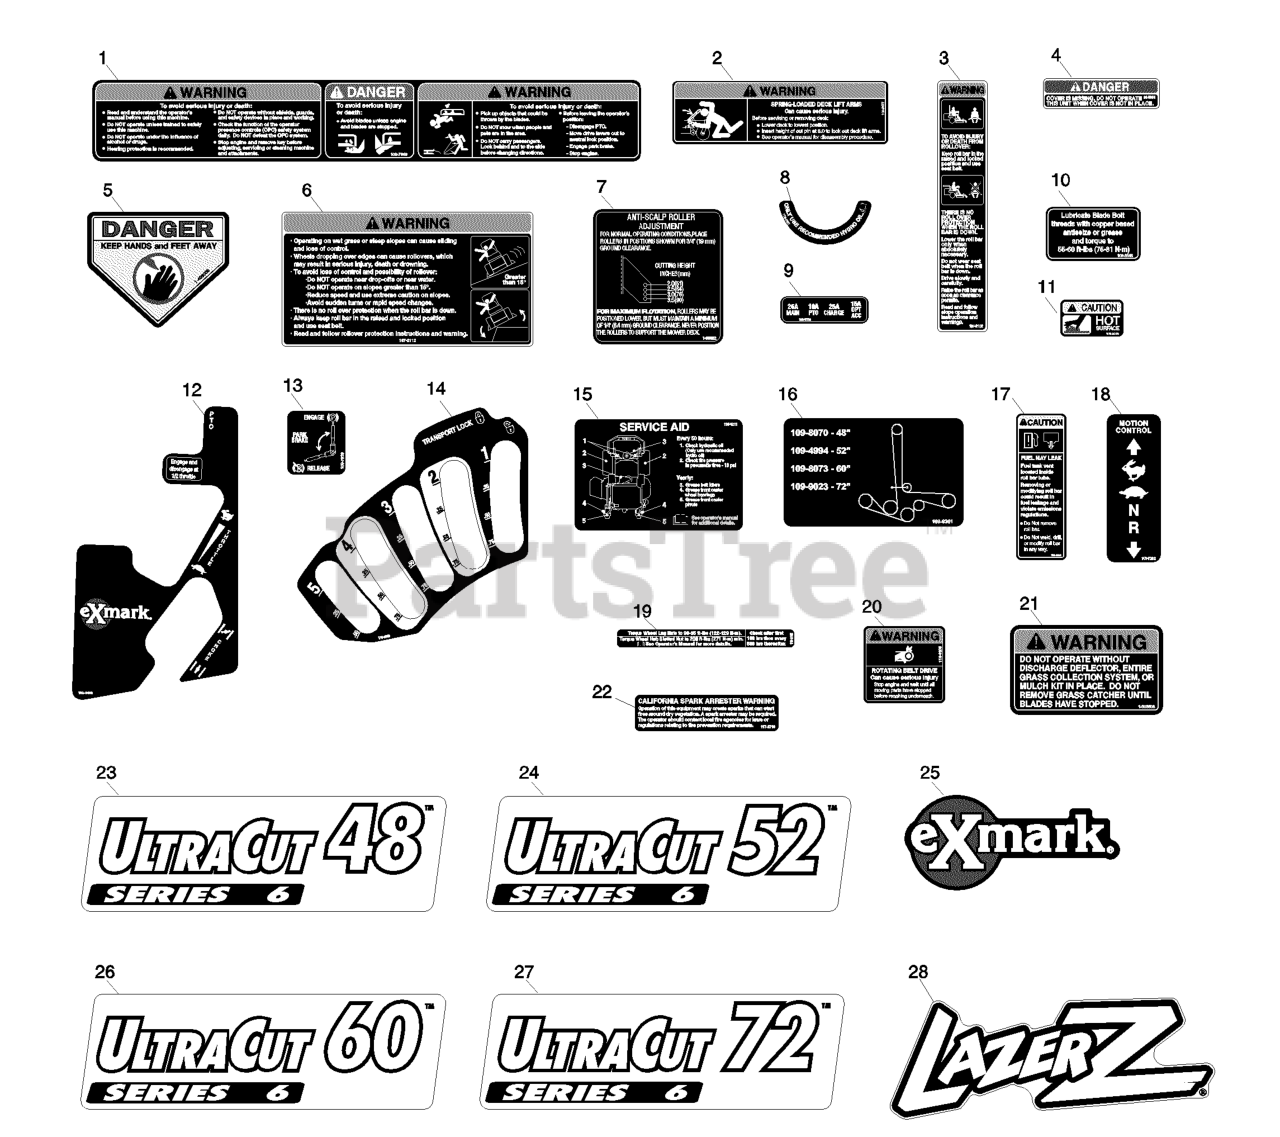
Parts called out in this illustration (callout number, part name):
1	DECAL-CONSOLE
2	DECAL-WARNING
3	DECAL-WARNING, FOLDING RO
4	DECAL-COVER, MISSING
5	DECAL-DANGER
6	DECAL-WARNING
7	DECAL,ANTISCALP
8	DECAL-HYDRO OIL
9	DECAL-FUSE
10	DECAL,BOLT TORQUE
11	DECAL-CAUTION
12	DECAL-CONTROL PANEL
14	DECAL-HOC
15	DECAL-SERVICE AID
16	DECAL,BELT ROUTING
17	DECAL-CAUTION
18	DECAL-MOTION CONTROL
19	DECAL-HUB, WHEEL
20	DECAL-BELT DRIVE
21	DECAL-WARNING, DISCHARGE
22	DECAL-ARRESTER, SPARK
23	DECAL,ULTRACUT 48 SERIES
24	DECAL,ULTRACUT 52 SERIES
26	DECAL,ULTRACUT 60 SERIES
27	DECAL,ULTRACUT 72 SERIES
28	DECAL,LAZER MODEL
